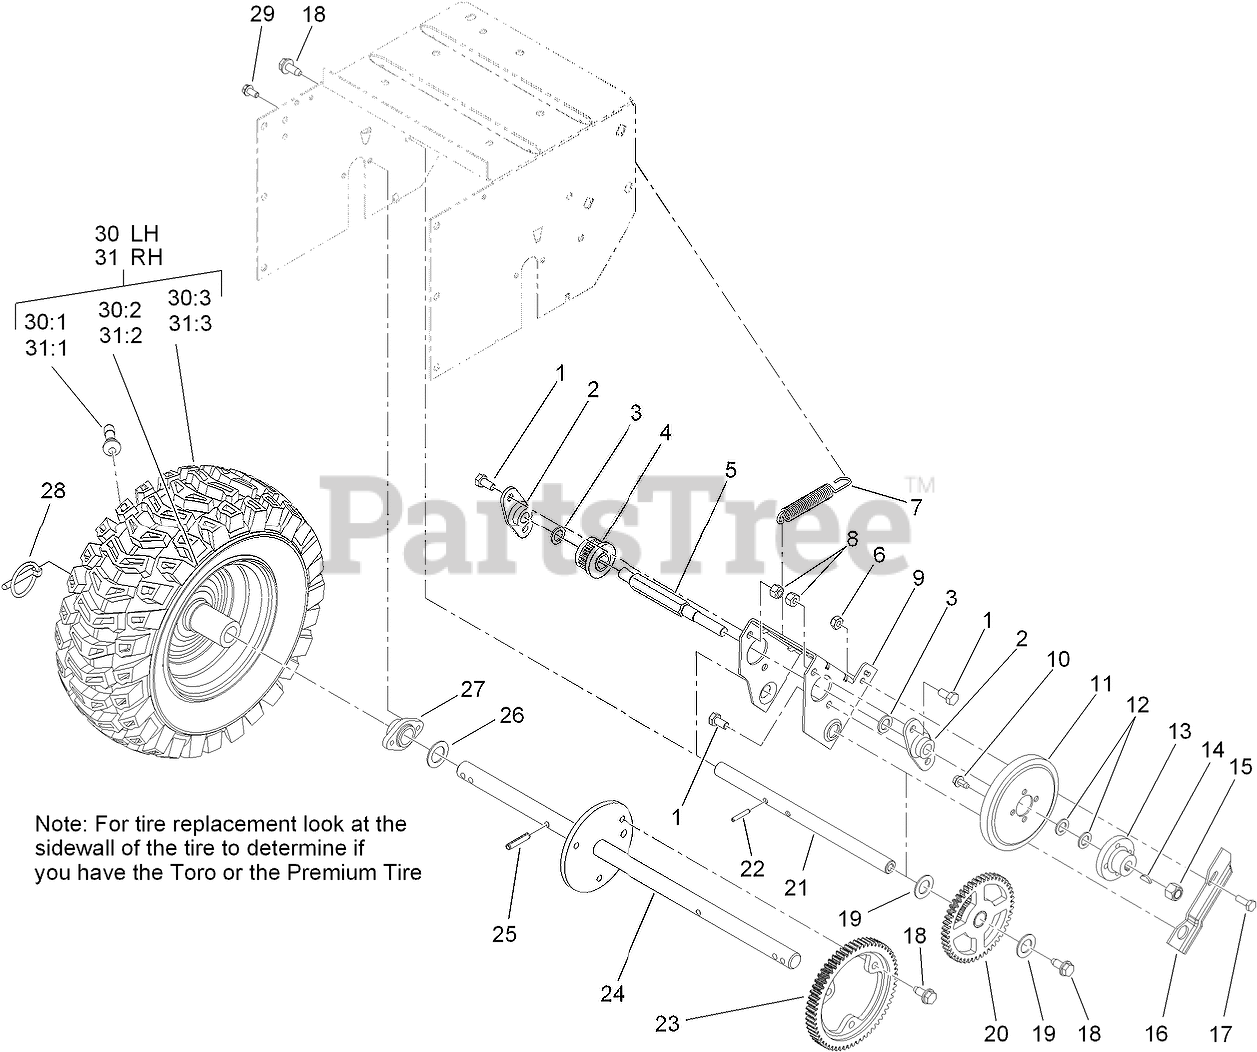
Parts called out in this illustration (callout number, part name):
1	SCREW-HH
2	BEARING-WHEEL, FRICTION
3	WASHER-FLAT
4	PINION
5	SHAFT-WHEEL, FRICTION
6	NUT-LOCK, NI
7	SPRING-TRACTION
8	NUT-LOCK, NI
9	BRACKET-SLIDING
10	SCREW-HWH
11	WHEEL-FRICTION
12	WASHER-THRUST
13	HUB-WHEEL, FRICTION
14	KEY-WOODRUFF
15	NUT-LOCK, NI
16	CAM-RECEIVER
17	SCREW-HH
18	SCREW-HWHTF
19	WASHER-SPECIAL
20	INTERNAL GEAR AND BUSHING ASM
21	SHAFT-PIVOT
22	PIN-SPRING
23	GEAR-AXLE
24	SHAFT-AXLE
25	PIN-ROLL, SLOTTED
26	WASHER-THRUST
27	BEARING-AXLE
28	PIN-LYNCH
29	SCREW-HWH
30	LH WHEEL AND TIRE ASM
30:1	STEM-VALVE
30:2	RIM-WHEEL
30:3	Tire (embossed with Toro)
30:3	Tire (embossed with Premium)
31	RH WHEEL AND TIRE ASM
31:1	STEM-VALVE
31:2	RIM-WHEEL
31:3	Tire (embossed with Toro)
31:3	Tire (embossed with Premium)
